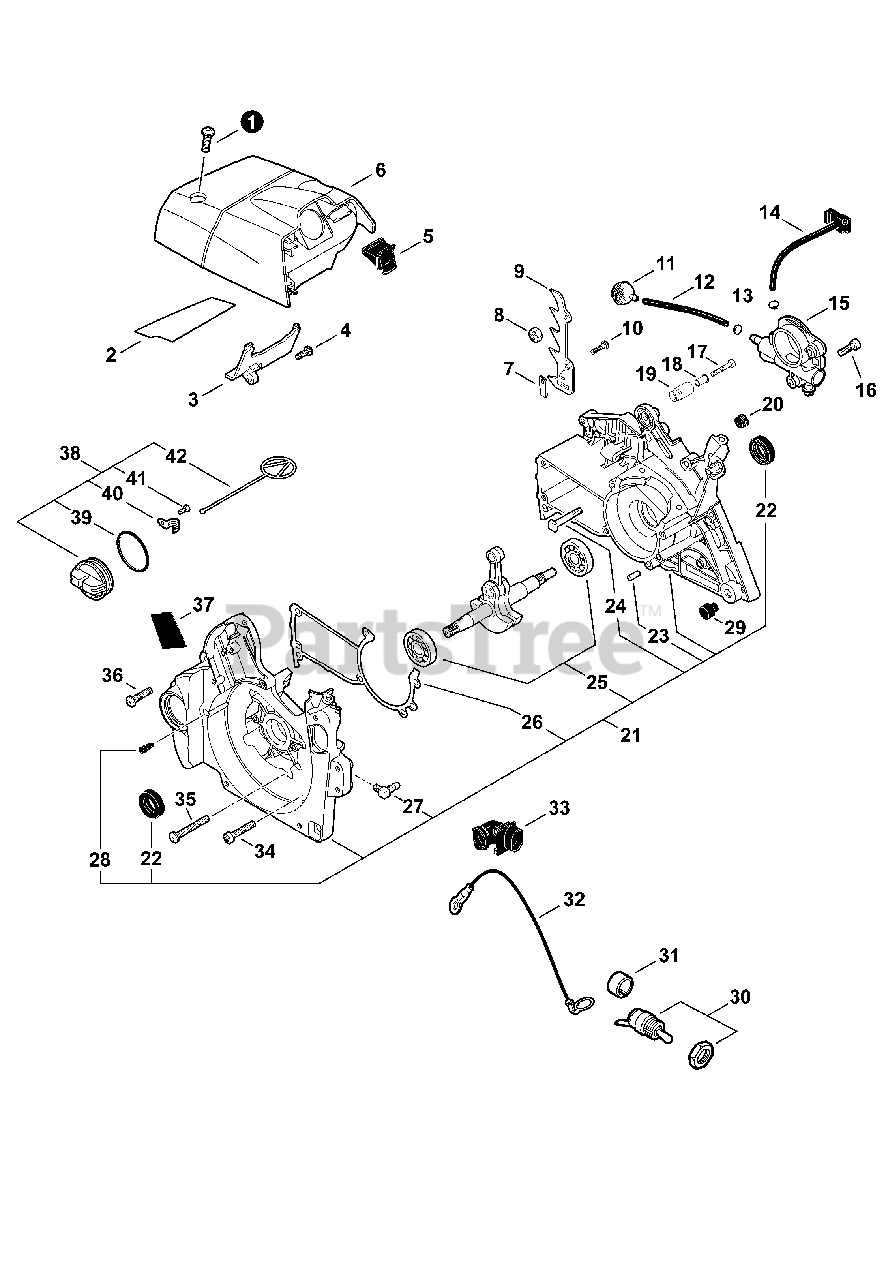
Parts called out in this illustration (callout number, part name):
1	BOLT, TORX 5×16
2	SHIELD, HEAT 75×32×0.15
3	GUIDE, AIR
4	BOLT, TORX 5×16
5	PIPE, INTAKE
6	COVER, ENGINE
8	NUT, LOCK M5
9	SPIKE, BUMPER
10	BOLT, TORX 5×16
11	FILTER, OIL
12	PIPE, FUEL 3×6×210 BLACK
13	CLIP Ø6
14	PIPE, OIL
15	AUTO-OILER ASSY
16	BOLT, TORX 4×12
17	BOLT, TORX 5×35
18	COLLAR 5
19	CHAIN CATCHER
20	GROMMET
21	CRANKCASE KIT
22	SEAL, OIL 15
23	PIN, LOCATING 5×10
24	BOLT, STUD M8×1.25×34.5
25	BEARING, BALL 6202
26	GASKET, CRANKCASE
27	CONNECTOR, PIPE
28	VENT ASSY
29	CUSHION
30	SWITCH, ON-OFF
31	CAP, SWITCH
32	LEAD - GROUND L= 170
33	PIPE, AIR INTAKE
34	BOLT, TORX 5×25
35	BOLT, TORX 5×35
36	BOLT, TORX 5×20
37	CUSHION
38	CAP ASSY, OIL
39	O-RING 28
40	RETAINER, CONNECTOR
41	SCREW, TAPPING 3×8
42	CONNECTOR, CAP L= 60 MM
